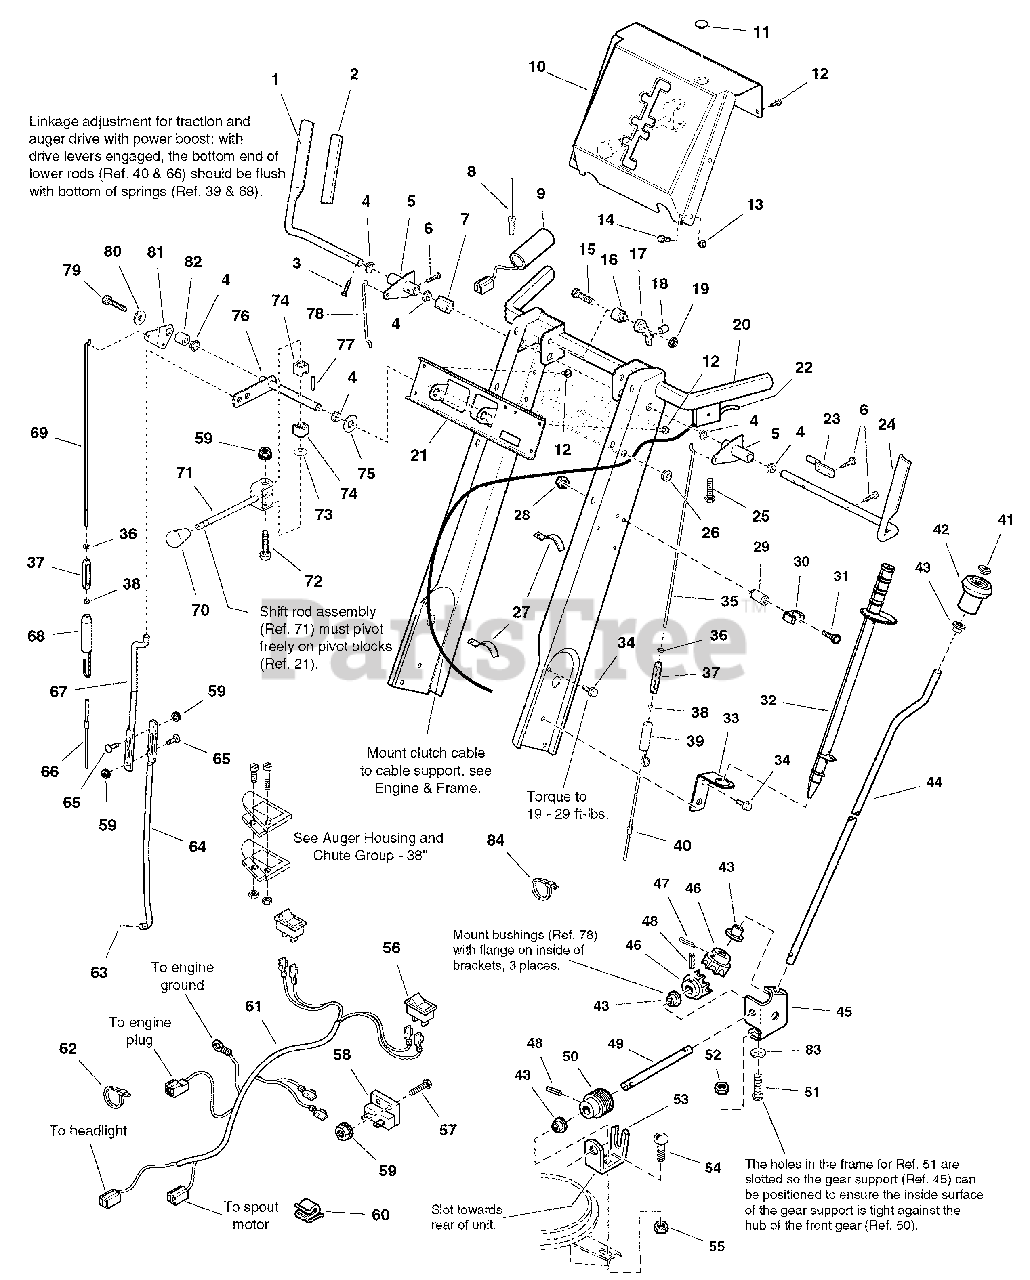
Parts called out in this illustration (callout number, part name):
1	HANDLE, Clutch R.H.
2	GRIP, Handle Clutch, Black
3	CAPSCREW, Hex Washer Head Taptite #10-24 x 1
4	BUSHING, 1/2 ID x 3/4 OD x 1/4, Nylon
5	LEVER & TUBE ASSEMBLY, Clutch
6	CAPSCREW, Hex Washer Head Taptite #12-24 x 1
7	GUIDE, Control
8	RIVET, Pop (1280 & 1390 Models Only)
9	GRIP, Black Soft 1" (9560, 1060 & 1170 Models Only)
9	HAND GRIP, Heated 1" (1280 & 1390 Models Only)
11	PLUG, Button (1390 Models Only)
12	CAPSCREW, Hex Washer Head Taptite 1/4-20 x 3/4
13	NUT, Hex Flange Whiz Lock 1/4-20
14	CAPSCREW, Hex Washer Head, 1/4-20 x 3/4 G5
15	CAPSCREW, Hex Flange Whiz Lock, 5/16-18 x 1-1/2
16	SPACER, 21/64 ID x 13/16 OD x 15/16
17	LATCH, Control
18	SPRING, Compression
19	NUT, Hex Flange 5/16-18 ESNA
20	HANDLE ASSEMBLY, Channel
21	BRACKET, Shift Control
22	CABLE & HANDLE ASSEMBLY, Clutch L.H.
23	ROD, Control 2" Flat
24	HANDLE, Clutch L.H.
25	SCREW, Pan Head Torx #10 x 1/2 Thick Cut
26	GROMMET, 1/2
27	CLIP, Wire
28	NUT, Hex Lock 10-24 with Nylon Insert NC3B
29	SPACER, 17/64 ID x 3/8 OD x 21/64
30	CLIP, Clean Out Tool
31	SCREW, Phillips #10-24 x 3/4
32	TOOL, Clean Out
33	BRACKET, Clean Out Tool
34	CAPSCREW, Hex Flange Whiz Lock, 5/16-18 x 3/4
35	ROD, Clutch, 17-5/16
36	NUT, Hex Machine Screw 10-24 NC-2B LH YEL
37	TURNBUCKLE, 2-1/4 Long #10-24NC (L.H. & R.H.)
38	NUT, Hex Machine Screw 10-24 NC-2B
39	SPRING, Extension 3-11/32 Long
40	ROD, Clutch, 6-5/16 Long
41	NUT, Push Pal (Used on all models Except 1390 Models)
42	KNOB, Spinner, Soft (9560, 1060, 1170 & 1280 Models Only)
43	BUSHING, 3/8 ID x 7/16 OD x 13/64, Nylon (9560, 1060, 1170 & 1280 Models Only)
44	ROD, Chute Control, 27" Long (9560, 1060, 1170 & 1280 Models Only)
45	SUPPORT, Gear (9560, 1060, 1170 & 1280 Models Only)
46	GEAR, Powered Metal (9560, 1060, 1170 & 1280 Models Only)
47	PIN, Cotter 1/8 x 1 (9560, 1060, 1170 & 1280 Models Only)
48	PIN, Spring 1/8 x 3/4 (9560, 1060, 1170 & 1280 Models Only)
49	ROD, Chute Worm, 18 Long (9560, 1060, 1170 & 1280 Models Only)
50	WORM, Chute, L.H. (9560, 1060, 1170 & 1280 Models Only)
51	CARRIAGE BOLT, 1/4-20 x 5/8 G5 (9560, 1060, 1170 & 1280 Models Only)
52	NUT, Hex Flange Whiz Lock, 1/4-20 Small (9560, 1060, 1170 & 1280 Models Only)
53	SUPPORT, Worm (9560, 1060, 1170 & 1280 Models Only)
54	CARRIAGE BOLT, 5/16-18 x 3/4 G5 (9560, 1060, 1170 & 1280 Models Only)
55	NUT, Hex KEPS Conical Washer, 5/16-18 (9560, 1060, 1170 & 1280 Models Only)
56	SWITCH, Hand Warmer (1280 & 1390 Models Only)
57	CAPSCREW, Hex Head, 1/4-20 x 3/4 G5 (1280 & 1390 Models Only)
58	RESISTOR BLOCK, Male Terminal (1280 & 1390 Models Only)
59	NUT, Hex KEPS, 1/4-20 Conical Washer
60	CLIP, Wire (Spout Rotator Models Only)
61	HARNESS, Wiring (Handwarmer Models Only)
61	HARNESS, Wiring (Handwarmer & Spout Rotator Models Only)
62	TIE, Self Locking 7-5/16 (1280 & 1390 Models Only)
63	PIN, Quick
64	ROD, Lower Shift 15-21/64 Long
65	CARRIAGE BOLT, 1/4-20 x 3/4 G5
66	ROD, Lower Clutch
67	ROD, Upper Shift 11-3/8 Long
68	SPRING, Extension 4-3/4 Long
69	ROD, Upper Clutch
71	ROD & CLEVIS ASSEMBLY, Shift
72	CAPSCREW, Hex Flange Whiz Lock 1/4-20 x 2-1/4
73	WASHER, Curved
74	BLOCK, Pivot, Powdered Metal
75	WASHER, 1/2
76	ROD & ARM ASSEMBLY, Pivot
77	CLIP, Hair Pin
78	ROD, Clutch 5-11/32 Long
79	CAPSCREW, Hex Flange Whiz Lock 5/16-18 x 1-1/2
80	WASHER, 5/16
81	LEVER, Clutch
82	SPACER, 21/64 ID x 3/4 OD x 53/64, Powdered Metal
83	NUT, Push for 1/4 Diameter Thread
84	TIE, Self Locking, 15" (Spout Rotator Models Only)
